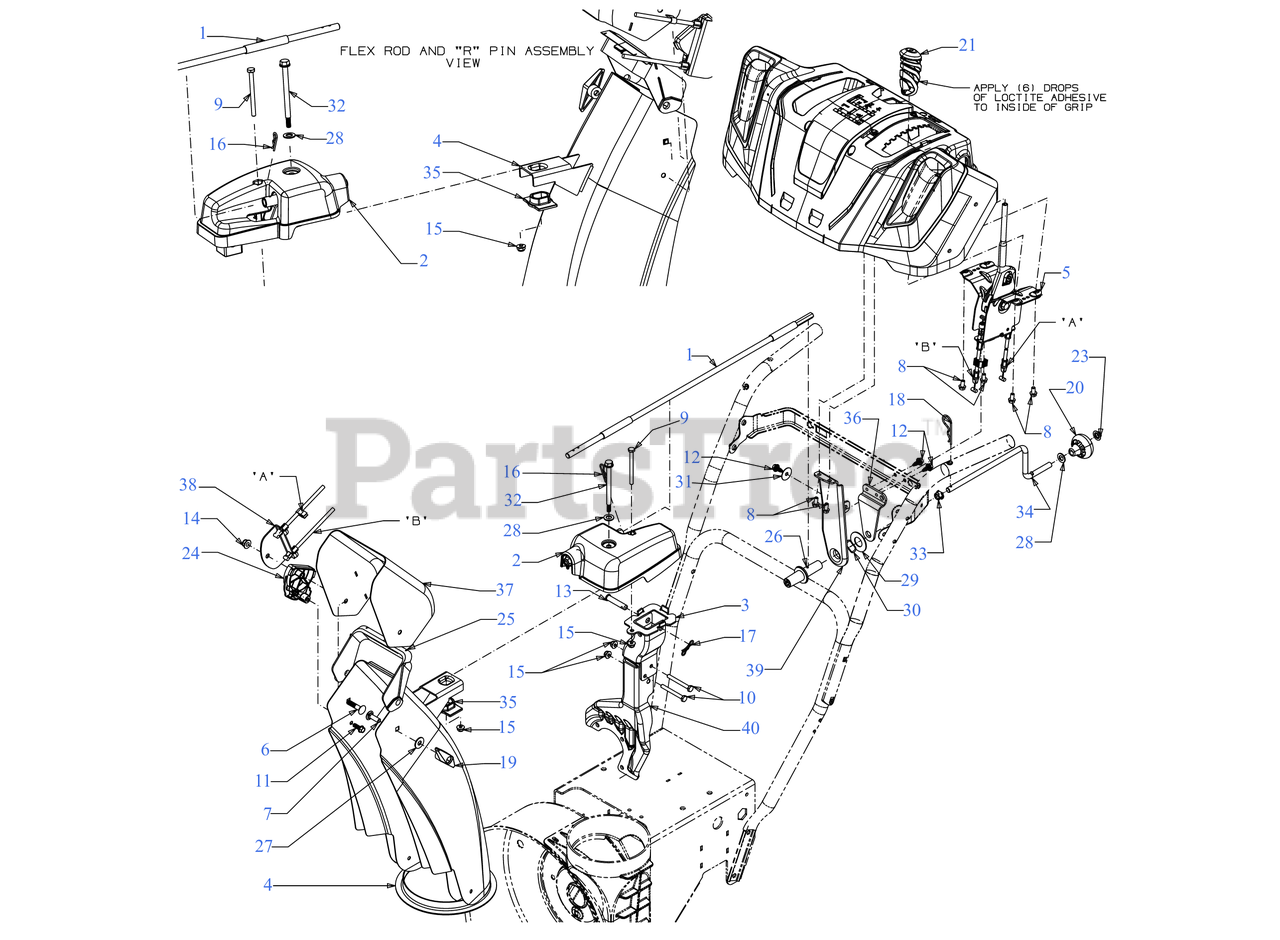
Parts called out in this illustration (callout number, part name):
1	CHUTE CONTROL SHAFT
2	GEARBOX ASSEMBLY
5	2-WAY STEEL CHUTE CONTROL ASSEMBLY
6	CARRIAGE BOLT 5/16-18 x 1.50
7	CARRIAGE BOLT 5/16-18 x 1.00
8	HEX SCREW 1/4-15 x .50
9	SCREW 1/4-20 x 3.0 GR5
10	SCREW 1/4-20 x 2.25 GR5
11	SCREW 1/4-15 x .750
12	SCREW 1/4-20X.625
13	CLEVIS PIN 3/8 x 1.87
14	FLANGE LOCK NUT 5/16-18
15	FLANGE LOCK NUT
16	INTERNAL COTTER PIN-1/2 DIA
17	BOW TIE COTTER PIN 1/4-5/16
18	INTERNAL COTTER PIN
19	WING KNOB NUT
20	SHIFT KNOB
21	PTO HANDLE GRIP .355 ID
23	PUSH NUT
24	CHUTE TILT GUIDE
25	UPPER CHUTE ADAPTER
26	CHUTE ROD COUPLER
27	FLAT WASHER
28	FLAT WASHER
29	FLAT WASHER
30	WAVE WASHER .785X1.00X.012
31	FLAT WASHER
32	SHOULDER SCREW
33	BUSHING .380 ID
34	CHUTE CRANK (POWDER BLACK)
35	HELICAL GEAR CHUTE ADAPTER
36	ROD SUPPORT BRACKET
